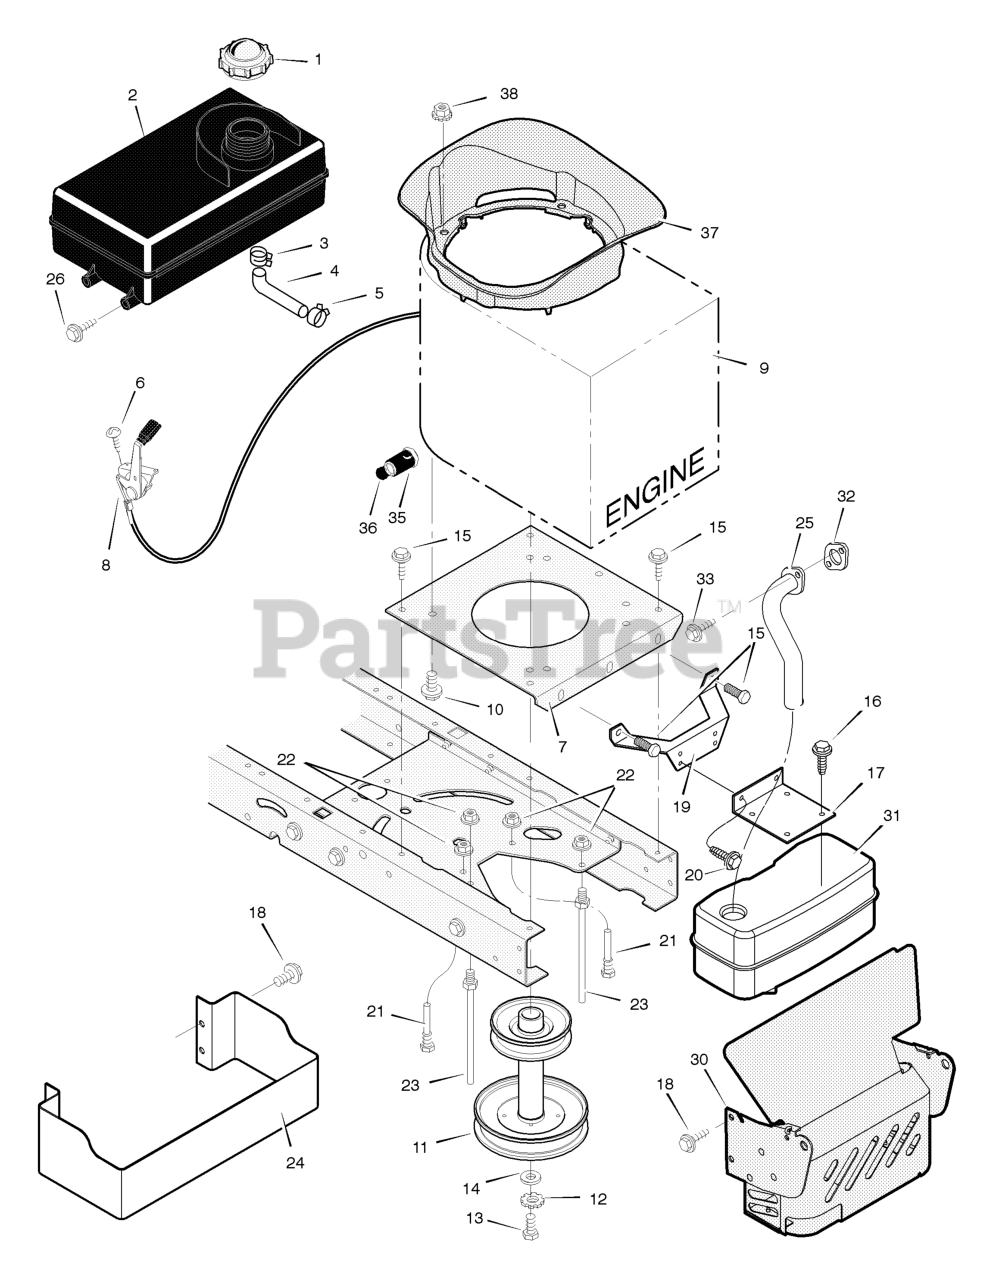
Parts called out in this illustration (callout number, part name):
1	Fuel Cap
2	TANK, Fuel 1.4 Gal.
3	Hose Clamp
4	Fuel Line (Must cut to length)
5	Hose Clamp
7	Plate, Engine
8	Throttle Control
9	Engine, Briggs & Stratton - INTEK *
10	Bolt, Engine Mount
11	STACK PULLEY ASSEMBLY
12	Lockwasher
13	Bolt, Hex
17	Bracket, Muffler
19	Bracket, Muffler Mount
21	Guide, Belt
22	Nut, Flange
23	Guide, Belt
24	GUARD, Heat Shield
25	Exhaust Tube, Single
30	Shield, Heat
31	Muffler
32	GASKET, Exhaust
35	Valve, Oil Drain
36	Cap, Oil Drain
38	Nut, Keps 1/4-20
